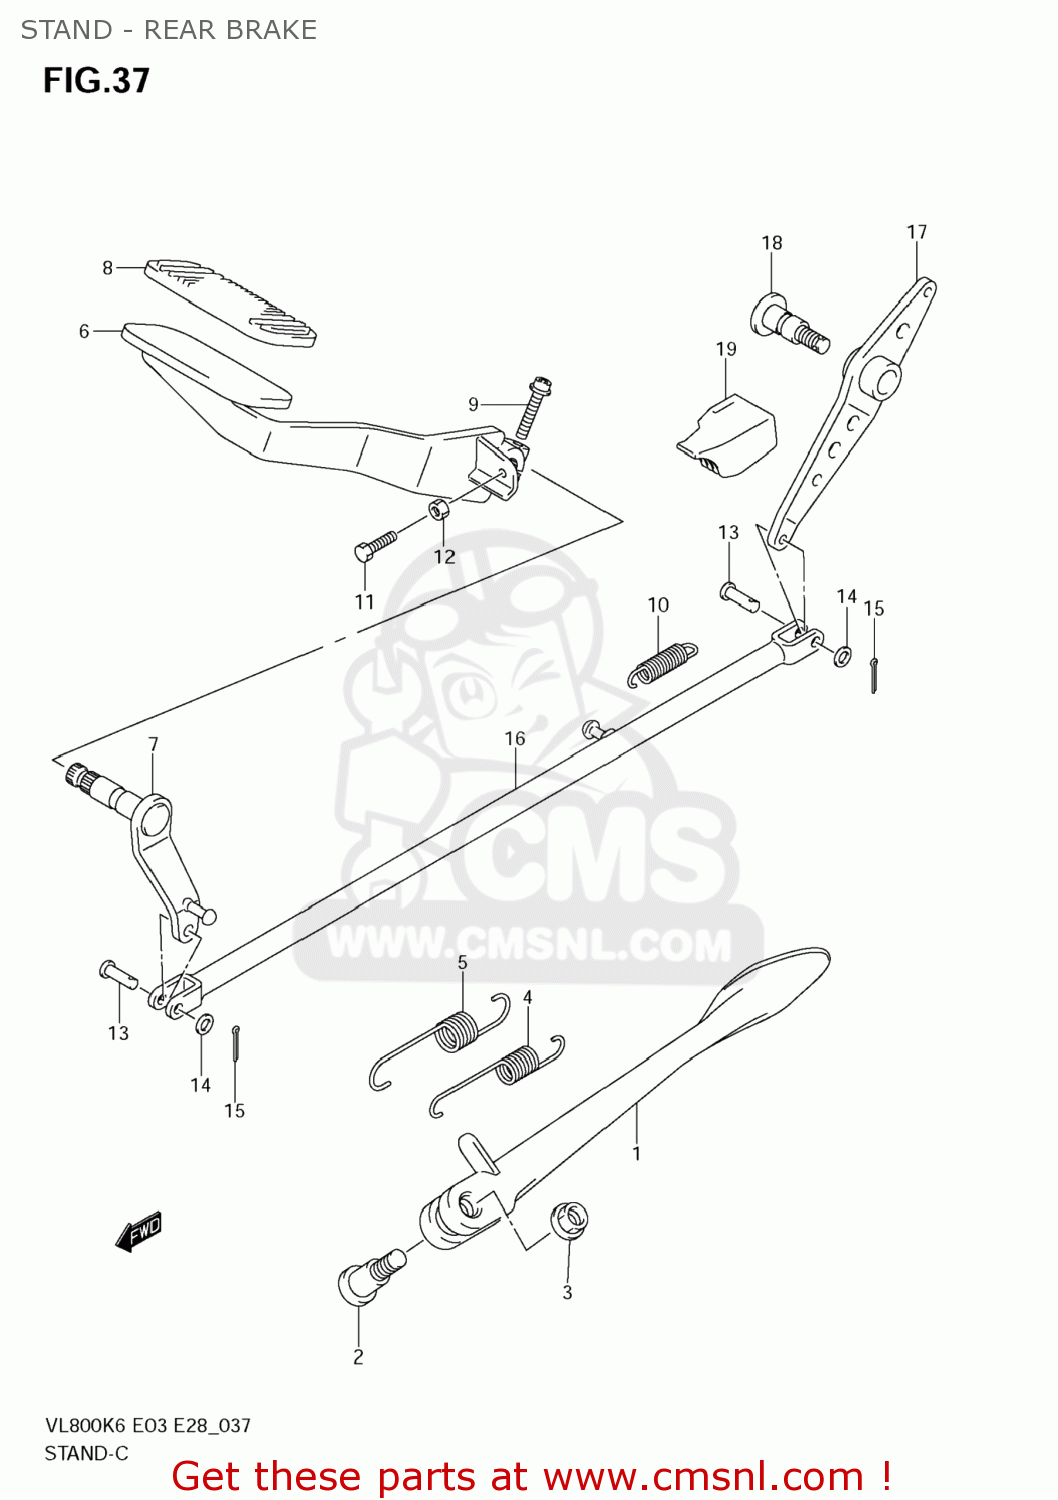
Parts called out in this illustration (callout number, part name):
1	STAND,PROP
2	BOLT(10X37.5)
3	NUT,PROP STAND
4	SPRING
5	SPRING
6	PEDAL,BRAKE
7	ARM,BRAKE ROD
8	RUBBER,BRAKE PEDAL
9	BOLT
10	SPRING
11	BOLT
12	NUT
13	PIN
14	WASHER
15	PIN
16	ROD,RR BRAKE FR
17	LINK,RR BRAKE
18	SHAFT,BRAKE PEDAL
19	RUBBER,BRAKE LINK
